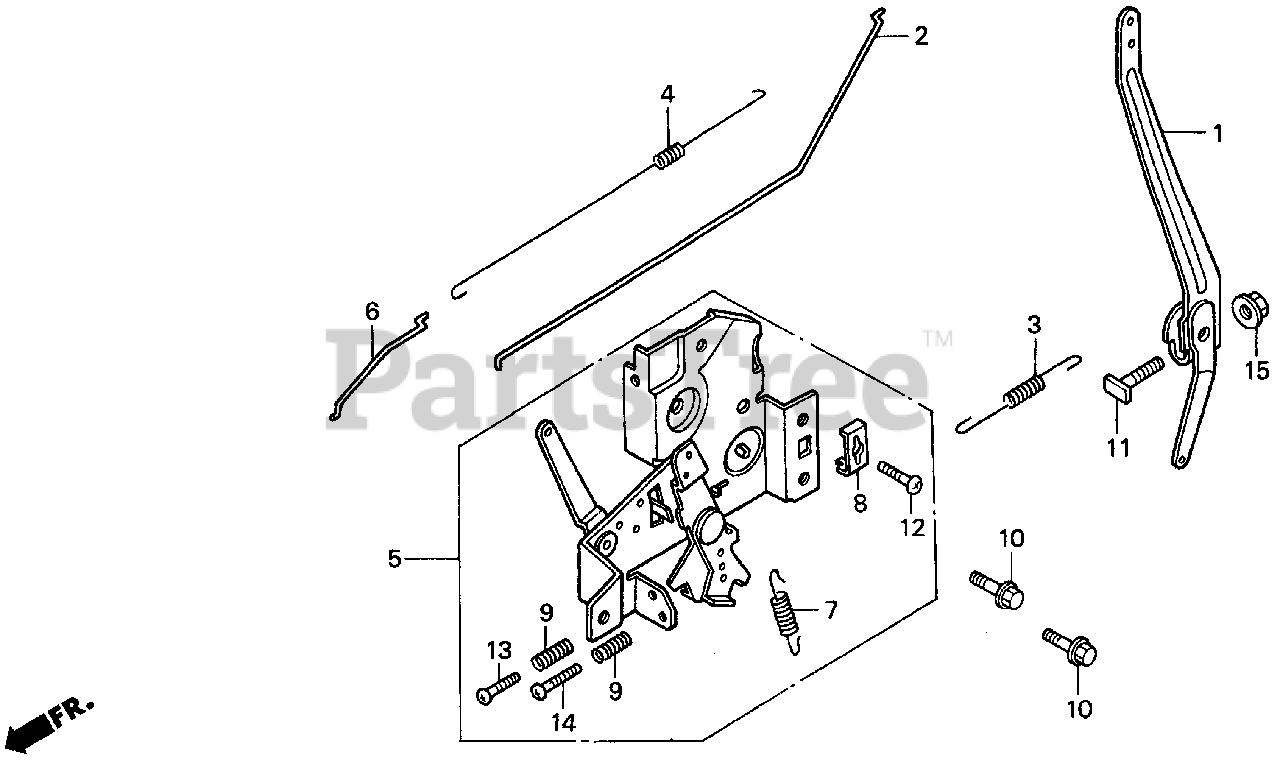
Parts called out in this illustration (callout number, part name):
1	ARM, GOVERNOR (C,G)
2	ROD, GOVERNOR
3	SPRING, GOVERNOR
4	SPRING, THROTTLE RETURN
5	CONTROL
6	ROD, CHOKE
7	SPRING, LEVER
8	HOLDER, CABLE
9	SPRING, CONTROL ADJUSTING
10	BOLT, FLANGE (6X14)
11	BOLT, GOVERNOR ARM
12	SCREW, PAN (5X16)
13	SCREW, PAN (5X20)
14	SCREW, PAN (5X25)
15	NUT, FLANGE (6MM)
